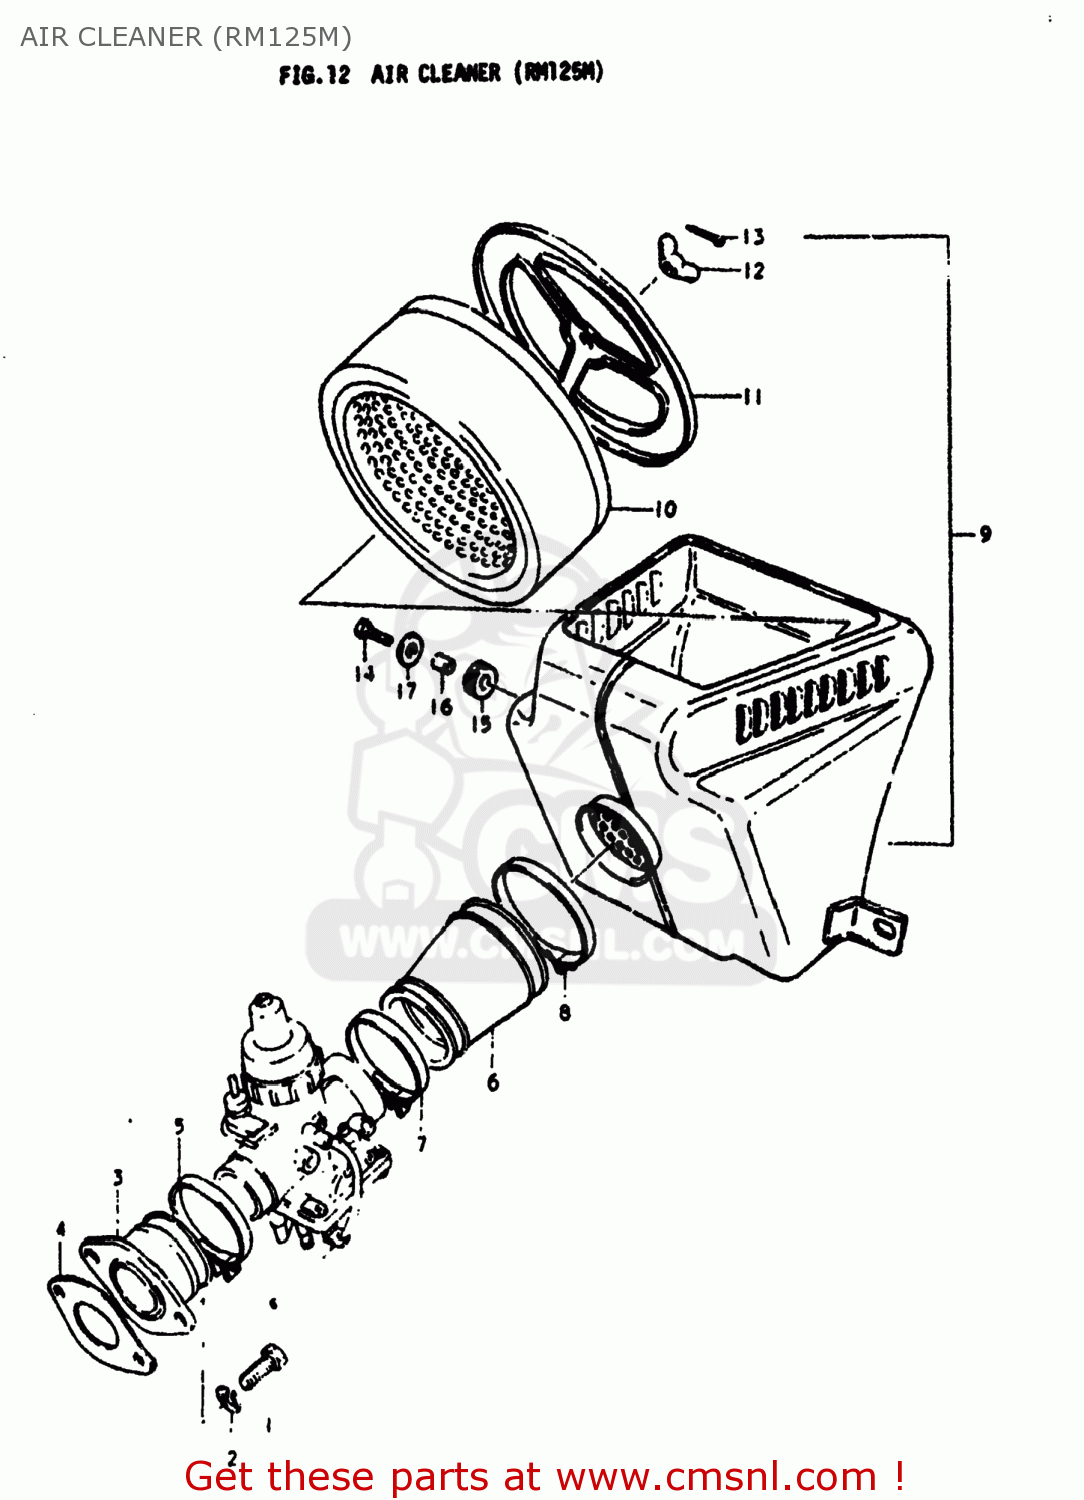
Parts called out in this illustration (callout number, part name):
1	BOLT
2	LOCK WASHER
3	PIPE,INTAKE
4	GASKET,CARBURETOR (MCA)
5	CLAMP
6	TUBE,AIR CLEANER OUTLET
7	CLAMP
8	CLAMP
9	CLEANER ASSEMBLY,AIR
10	FILTER,AIR CLEANER
12	NUT
14	BOLT
15	CUSHION
16	SPACER (7X9X7)
17	WASHER (6.5X20X1.2)
